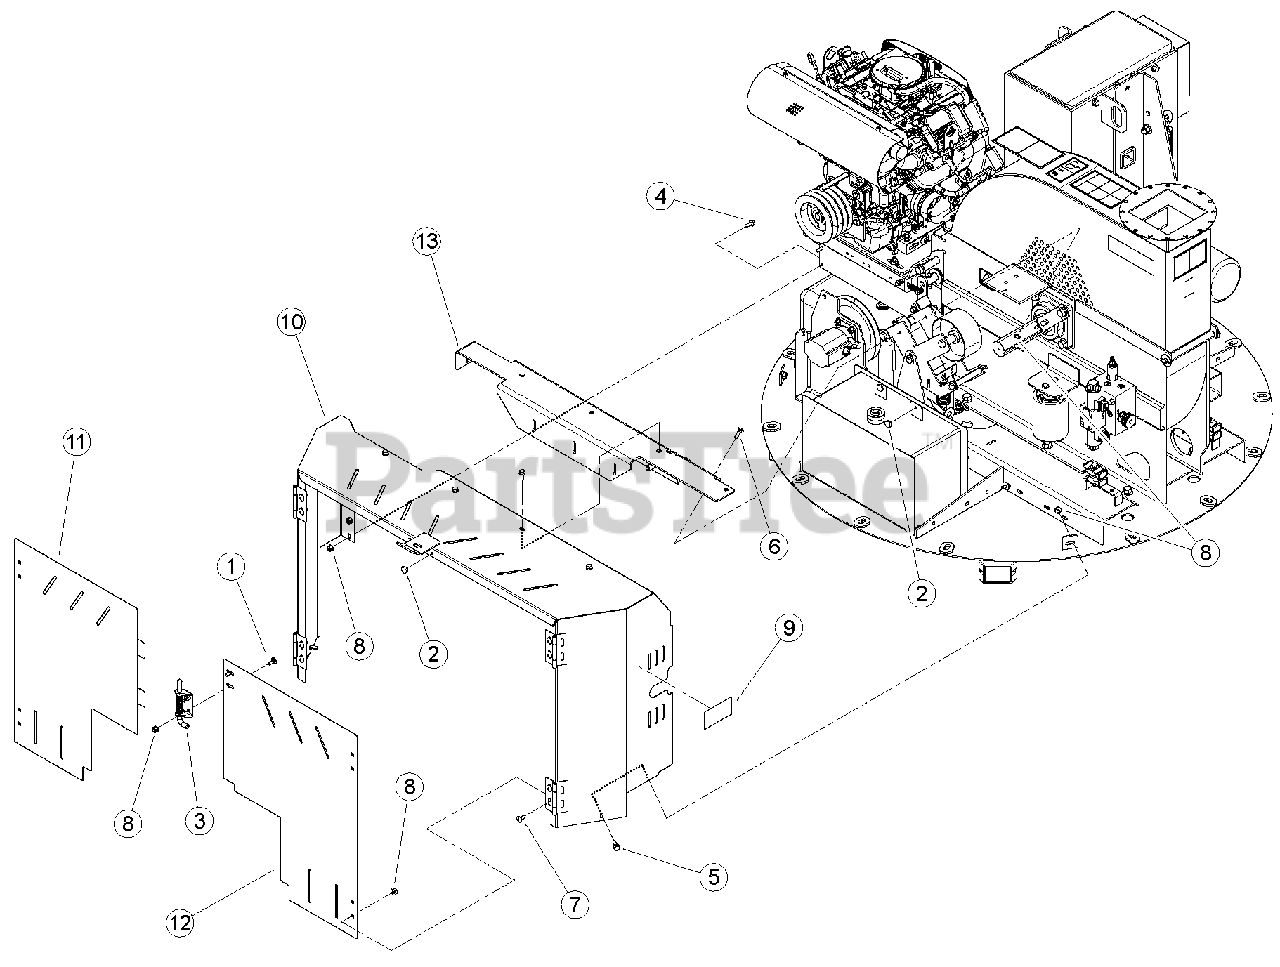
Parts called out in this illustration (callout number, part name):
1	BOLT, 5/16-18 X 3/4 GR5 CRG SN
2	BUMPER, RUBBER
3	LATCH, RH HINGE
4	BOLT, 5/16 X 3/4 FLANGE NC
5	BOLT, 5/16 X 1 FLANGE NC
6	BOLT, 5/16" X 1" GR5 CRG ZP
7	BOLT, 5/16 X 3/4 GR5 CRG NC ZP
8	NUT, 5/16-18 NYLOCK-FLANGE
9	DECAL, FEED SPEED
10	WELDMENT, BELT SHIELD FRAME
11	WELDMENT, 8" LEFT DOOR
12	DOOR, 8" RIGHT
13	WELDMENT, ENGINE TIE
